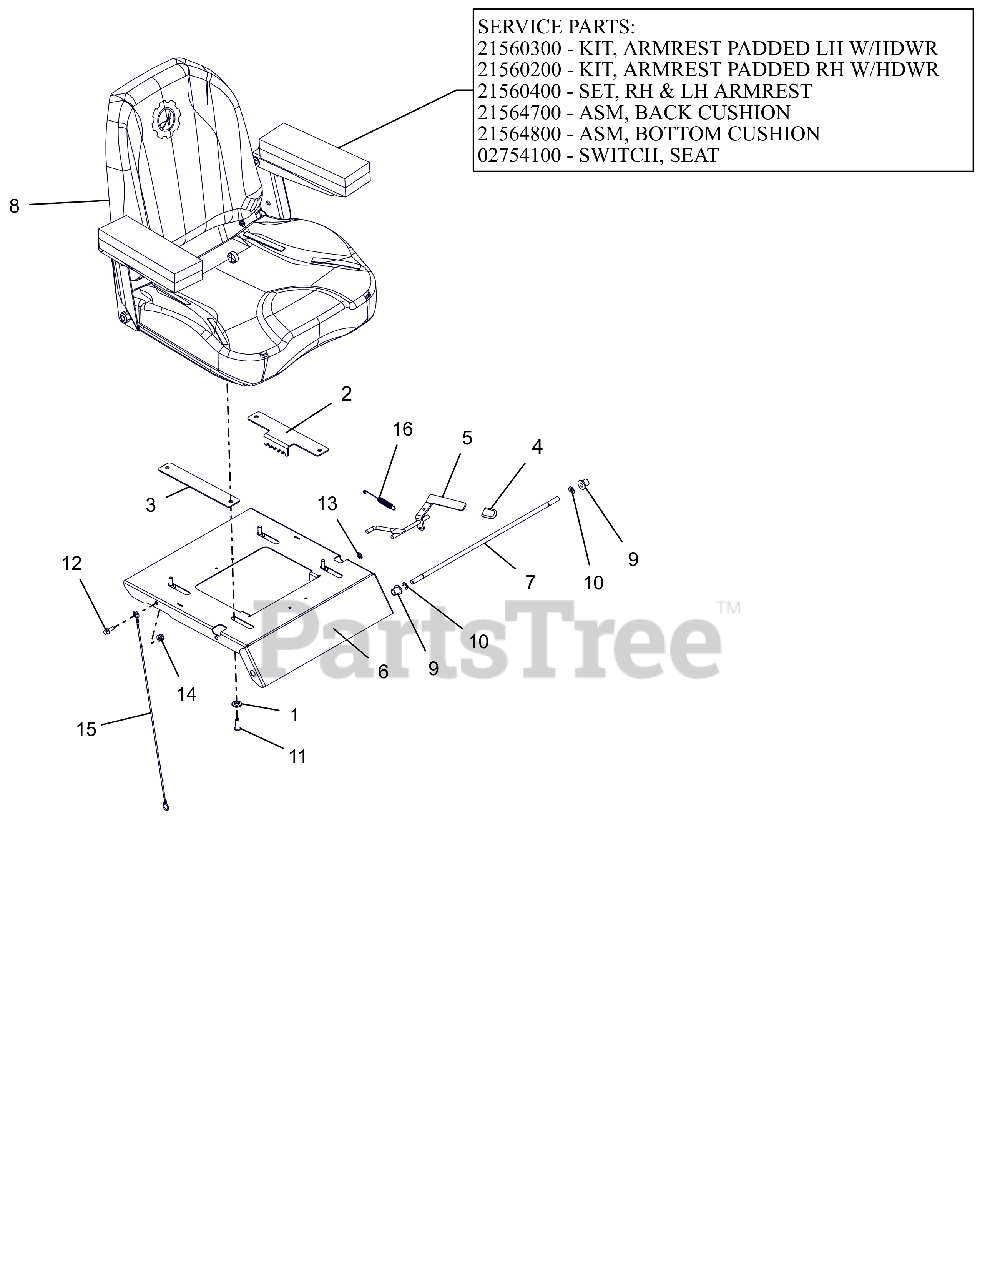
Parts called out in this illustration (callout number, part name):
1	BSHG, FLG .325X.499X.26X.88
2	PLATE, ADJUSTABLE SEAT TRACK
3	PLATE, ADJUSTABLE SEAT SLIDE
4	GRIP, SEAT LEVER, GREY
5	WLDMT, ADJUSTABLE SEAT LATCH
6	PLATE, SEAT
7	ROD, SEAT PIVOT
8	SEAT, IKON XL
8	PAD,LH ARMREST LIGHT GREY SOFT
8	PAD, RH ARMREST LIGHT GREY
8	SET,RH & LH ARMREST -LTGREY
8	ASM, BACK CUSHION-ARIENS X
8	ASM, BOTTOM CUSHION-ARIENS X
8	SWITCH- SNAP MTG N.O.
9	BSHG-FLG .38X.580X.667X.750
10	RG-RTNG-EXT .375X.035 TYP E
11	SCR-SKH .31-18X1.0 BTNHD YWZC
12	BLT,HEX-FLG .25-20X.75 G5 BFP
13	NUT-PUSH .312
14	@NUT-LK-NYL-FLG .31-18 YWZC
15	LANYARD, SEAT CABLE .093X19.5
16	SG-TENS .043X.44X3.31 WLD 5.8
